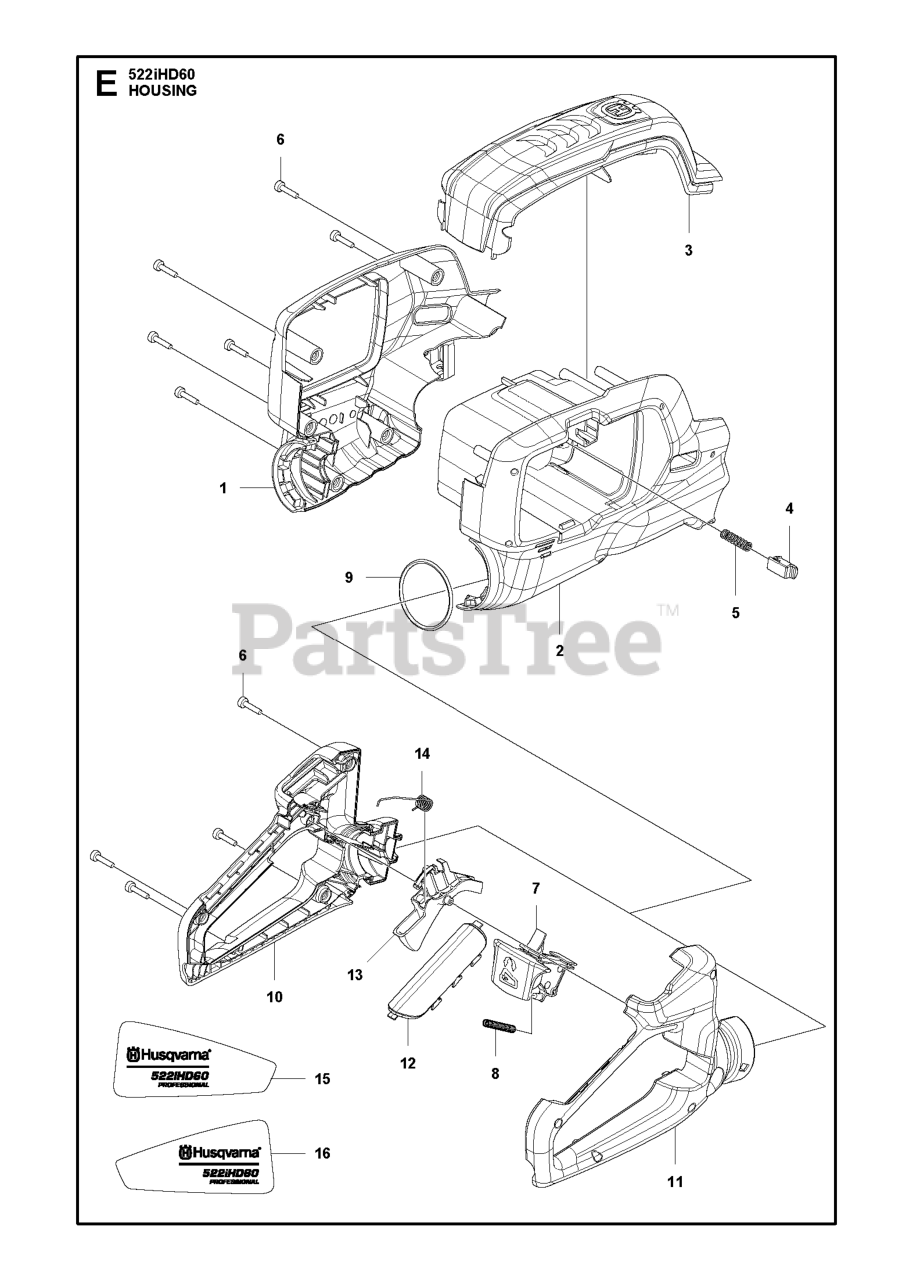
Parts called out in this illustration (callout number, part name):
4	PUSH BUTTON
5	SPRING PUSH OUT
6	SCREW ITXSCT PW4.2X18 10.9 ZN
8	RECOIL SPRING RECOIL SPRING RE
